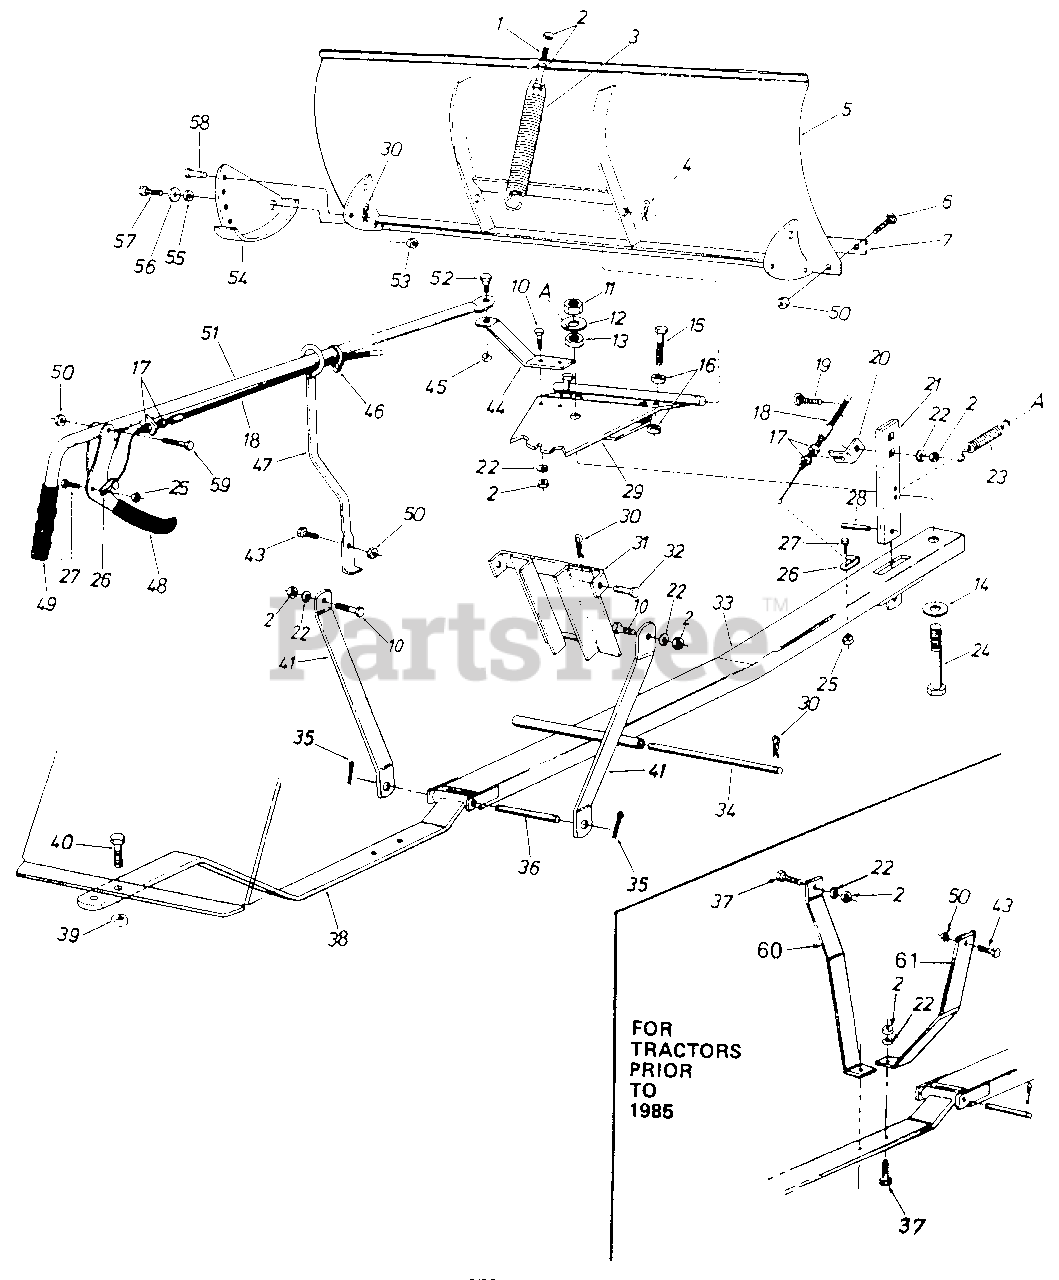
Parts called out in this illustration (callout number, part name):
1	Hex Scr. 3/8-16 x 4.50" Lg.*
2	Hex Nut 3/8-16 Thd.*
3	Blade Adjustment Spring
4	Hairpin Clip 5/32" Dia.
5	48" Blade Ass'y.
6	Carriage Bolt 5/16-18 x 75" Lg.*
7	Wear Plate 48"
10	Hex Scr. 3/8-16 x 1.00" Lg.*
11	Hex L.-Nut 3/4-10 Thd.
12	Fl.-Wash. .810" I.D. x 2.00" O.D.
13	Hex Jam Nut 3/4-10 Thd.*
14	Fl.-Wash. .810" I.D. x 2.00" O.D.
15	Hex Scr. 1/2-13 x 2.00" Lg.*
16	Hex Nut 1/2-13 Thd.*
17	Hex Jam Nut 5/16-24 Thd.*
18	Control Cable Ass'y.
19	Carriage Bolt 3/8-16 x 1.25" Lg.*
20	Cable Guide Bracket
21	Angle - Lock Bar
22	L.-Wash. 3/8" I.D.
23	Angle Lock Spring
24	Hex Scr. 3/4-10 x 4 00" Lg.
25	Hex L.-Nut 1/4-20 Thd.
26	Clevis Lanyard Fitting
27	Hex Scr. 1/4-20 x .75" Lg.
28	Roll Pin 1/4" Dia. x 1.00" Lg.
29	Pivot Plate Ass'y.
30	Hairpin Clip 3/32" Dia.
31	Guide Bracket Ass'y.
32	Clevis Pin 1 2" Dia. x 1.00" Lg.
33	Push Bar Ass'y.
34	Lift Shaft
35	Cotter Pin 5/32" Dia. x 1.00" Lg.
36	Pivot Shaft
37	Hex Scr. 3/8-16 x 1.25" 4
38	Hanger Bracket Ass'y.
39	Hex L.-Nut 5/8-11 Thd
40	Hex Scr. 5/8-11 x 1.50" 4.
41	Hanger Link
43	Hex Bolt 5/16-18 x 1.00" Lg.
44	Blade Pivot Bracket
45	Hex L.-Nut 3/8-16 Thd.
46	Nylon Cable Tie
47	Tube Guide Ass'y.
48	Clutch Grip Ass'y.
49	Grip-3/4" Handle
50	Hex L-Nut 5/16-18 Thd.
51	Tube Handle Ass'y.
52	Shld. Scr.-Special 3/8-16 Thd.
53	Hex L.-Nut 3/8-16 Thd.
54	Skid Assembly
55	Spacer
56	Fl.-Wash. .385" I.D. x 1.00" O.D.
57	Hex Scr. 3/8-16 x4 .75" Lg.
58	Clevis Pin 5/16" Dia. x .75" Lg.
59	Hex Scr. 5/16-18 x 1.50" Lg.
60	Mounting Brkt.-L.H.
61	Mounting Brkt-R.H.
